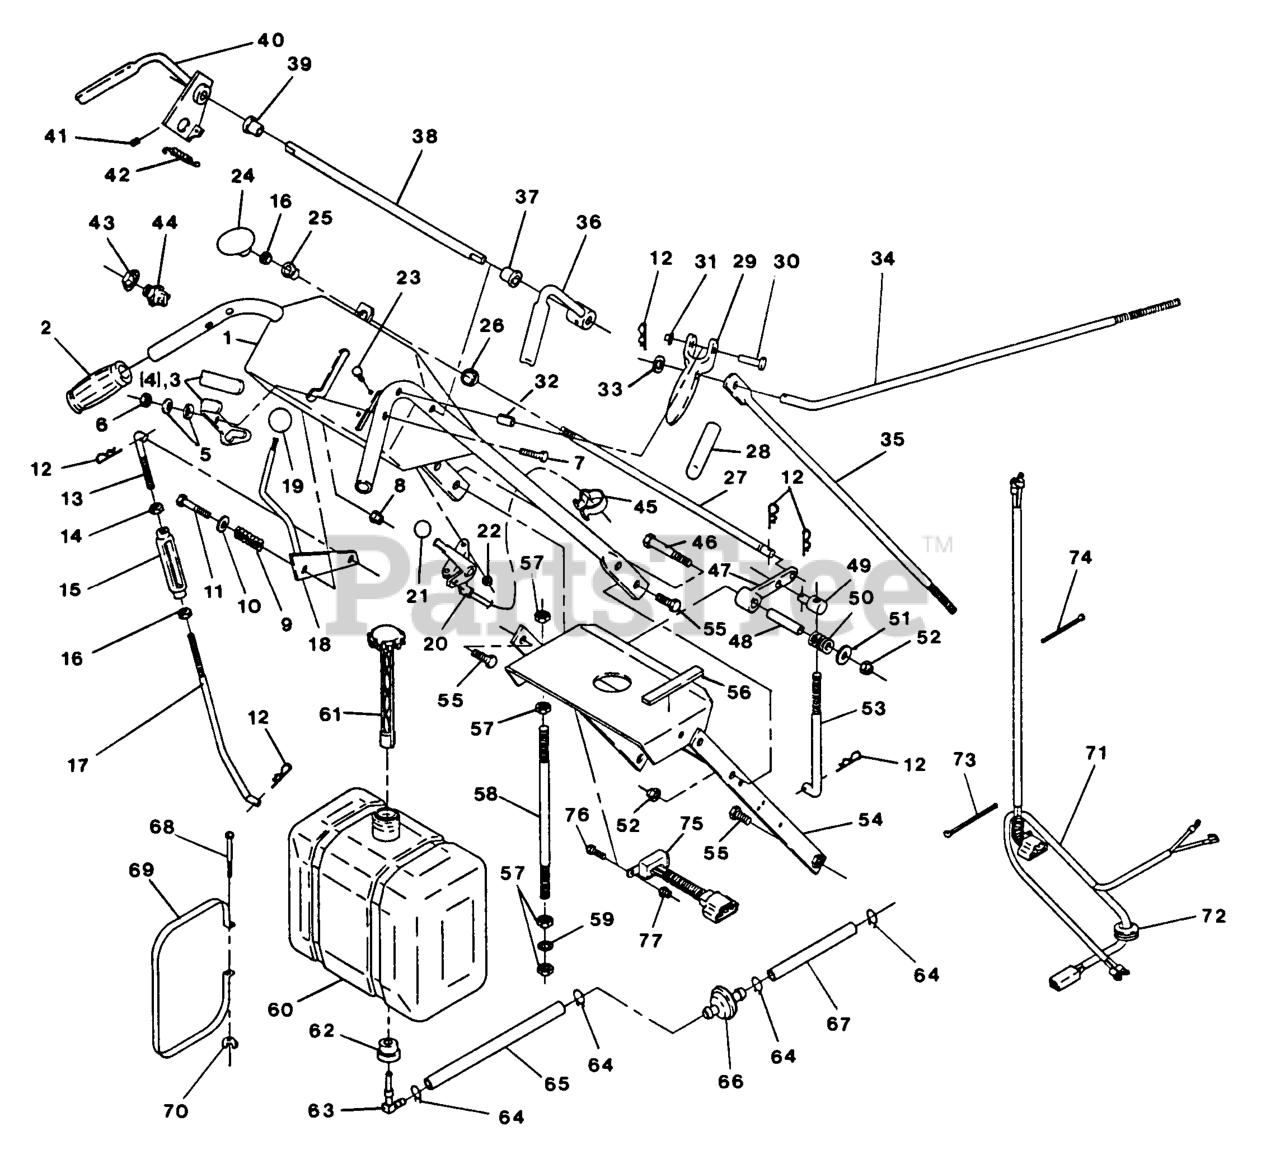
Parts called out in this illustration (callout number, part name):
3	LATCH,W/GRIP RH
4	LATCH,W/GRIP LH
5	WASHER-SPRING
6	NUTTORQUE ZNKPLT
12	PIN-COTTER
13	ROD,PTO RH LOW LH THD
17	ROD,PTO LOW RH THD
19	KNOB-BALL
20	CABLE,THROTTLE CONTROL
21	KNOB-BALL
23	BOLT-CARR
24	KNOB-PUSH / PULL
25	BEARING-NYLON
26	NUT-PUSH
28	GRIP-LEVER, DRIVE
29	DRIVE LEVER ASM
30	PIN-LEVER, DRIVE
31	NUT-PUSH
32	PIN-ROLL
34	LINKAGE,BRAKE
35	LINKAGE,CALIPER
37	BUSHING-NYLON
38	ROD,CONNECTING
39	BUSHING,FLANGED
41	SCREW-SET
42	SPRING-EXTENSION
44	SWITCH,OPERATOR CNTRL
45	CLIP-CABLE
49	SWIVEL,SHORT ADJUSTING
50	SPRING-COMPRESSION
56	PAD,PLASTIC TANK
68	SCRW,MACH CRPH
70	WINGNUT
72	GROMMET
73	TIE-PLASTIC
74	TIE-CABLE
